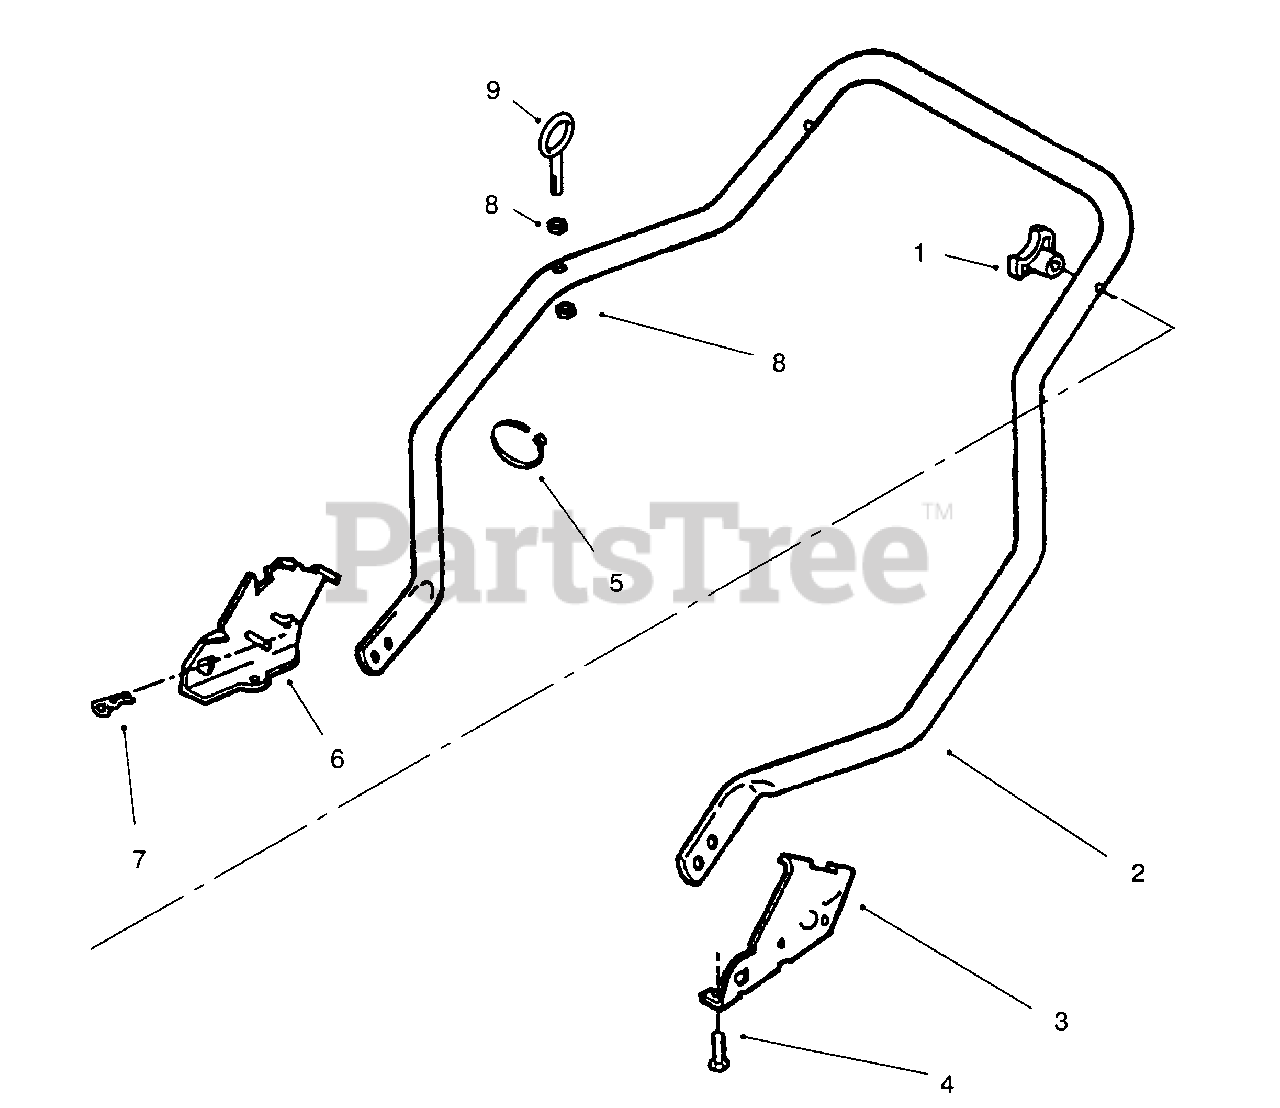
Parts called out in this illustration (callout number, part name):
1	Knob
2	Handle-Lower
3	Bracket-Handle L.H.
5	Tie Strap
6	Bracket-Handle R.H.
7	Pin-Cotter
8	Nut-Lock
9	EyeBolt
